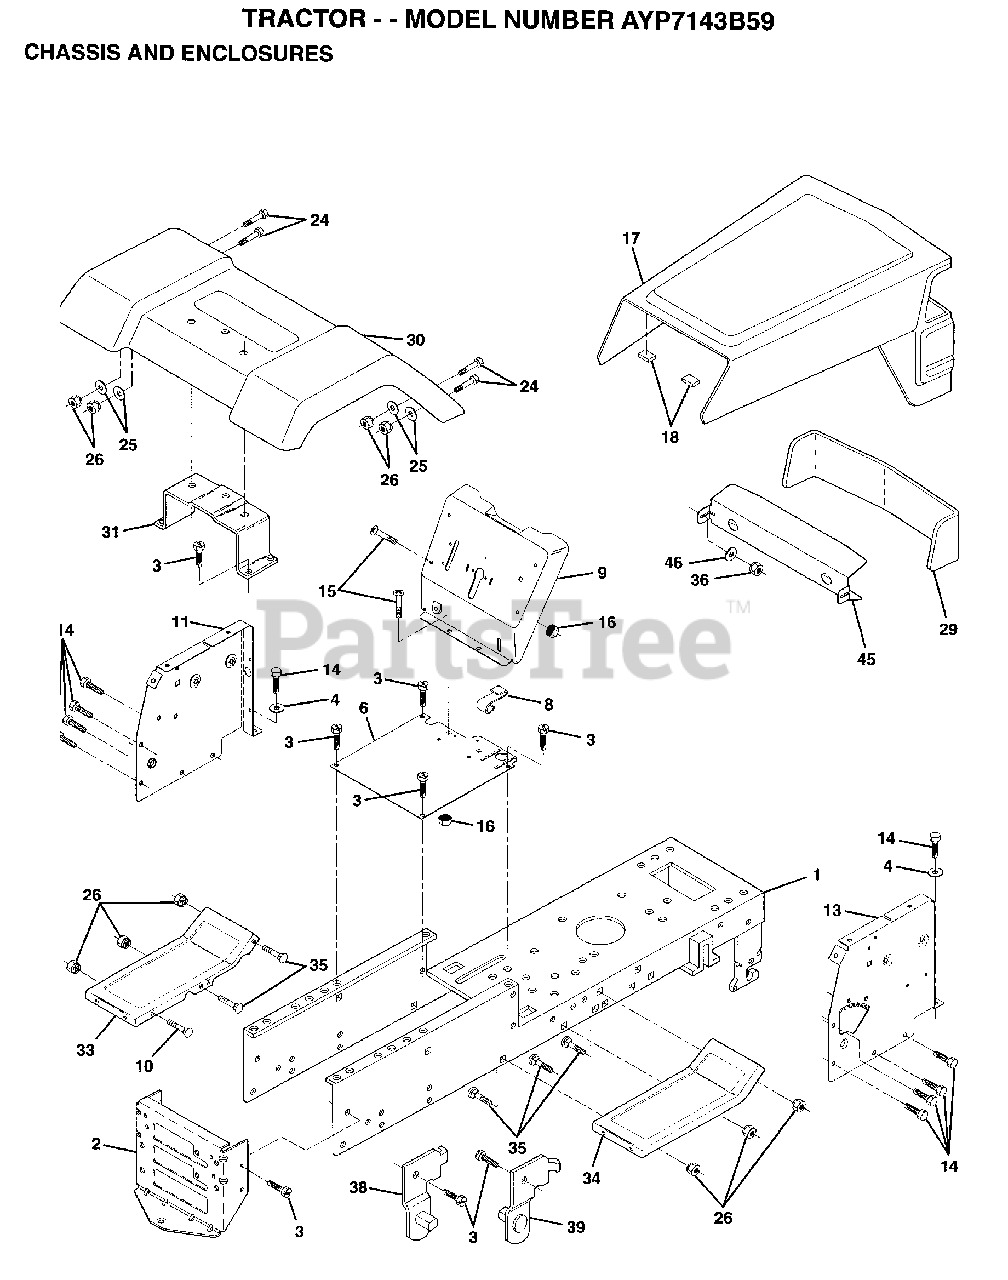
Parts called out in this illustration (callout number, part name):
1	CHASSIS.WLD.11GA
3	SCREW
4	WASHER
8	"CLIP,INSULATOR"
9	DASH SILKSCRN 1
11	DASH PANEL LH
14	SCREW LT
15	SCREW
17	HOOD/GRILL ASM
24	BOLT
25	WASHER
26	NUT
30	FENDER
31	BRKT FENDER
33	FOOTREST LH
34	FOOTREST RH
35	BOLT
36	PAL NUT LT
38	BRACKET ASM LH
39	BRACKET ASM RH
46	RETAINER
